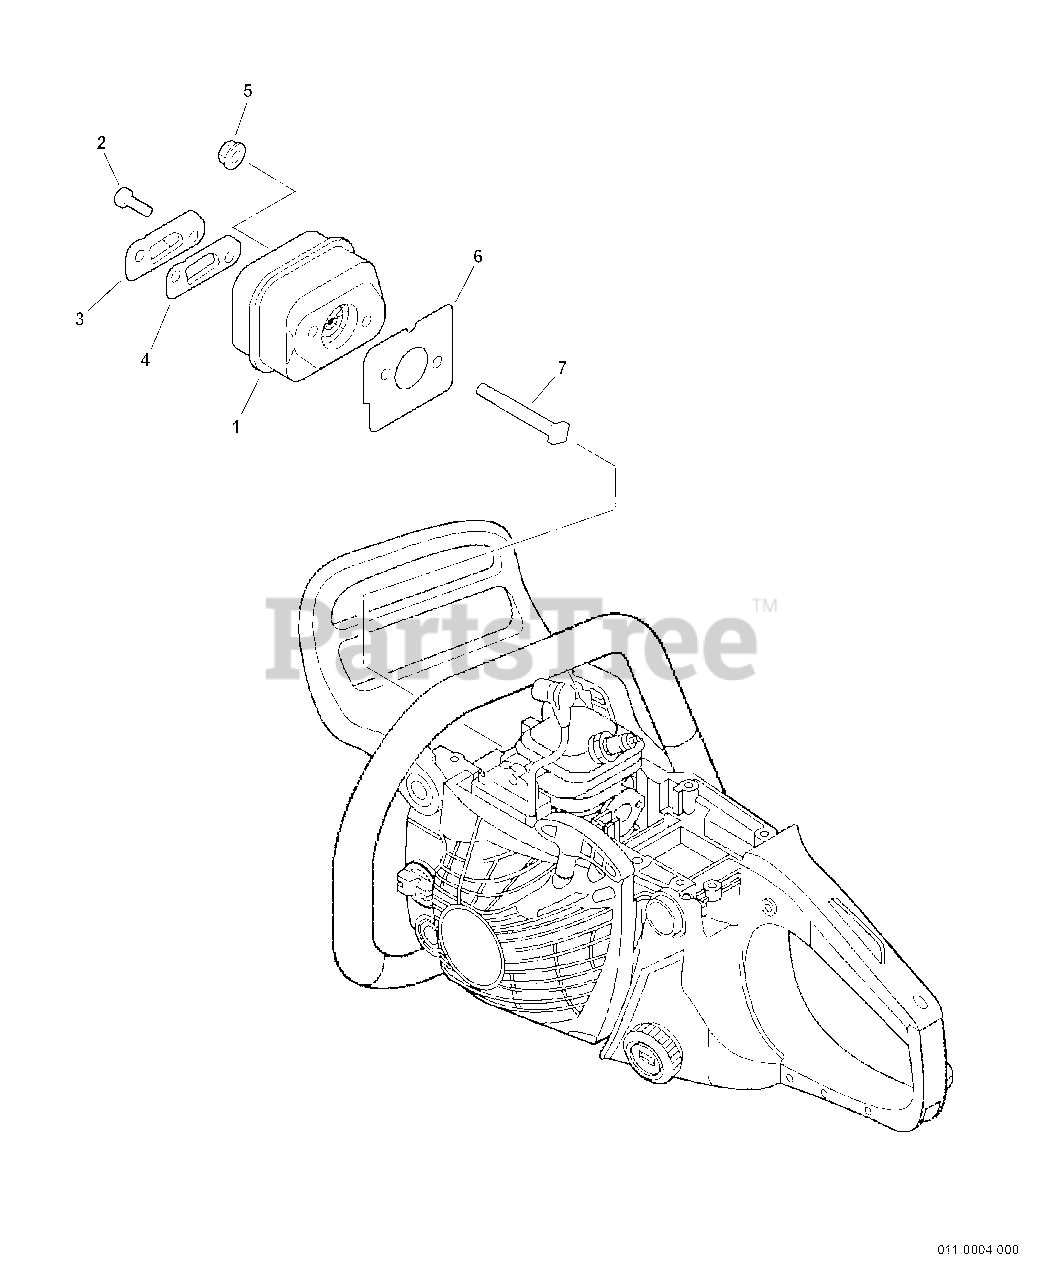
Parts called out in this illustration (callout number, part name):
1	MUFFLER
2	SCREW 4×8
3	GUIDE, EXHAUST
4	SCREEN, SPARK ARRESTER
5	NUT, FLANGE M5
6	GASKET, EXHAUST
7	BOLT 5×60
